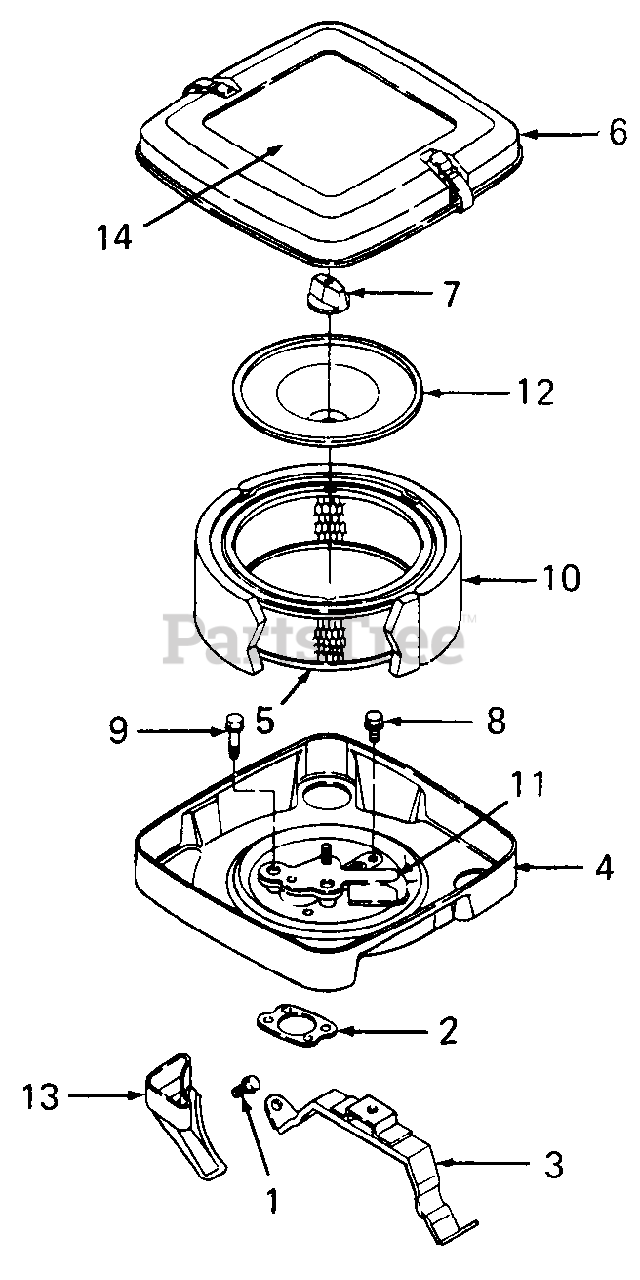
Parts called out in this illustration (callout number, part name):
1	Screw, Sems
2	Gasket, Air Cleaner
3	Bracket, Air Cleaner
4	Base, Air Cleaner
5	Cartridge, Air Cleaner
6	Cover, Air Cleaner
7	Knob, Air Cleaner
8	Screw, Sems
9	Screw, Sems
10	Element, Foam
11	Shield Assy
12	Plate, Air Cleaner
13	Tube, Air Inlet
14	Label, Vanguard Engine
